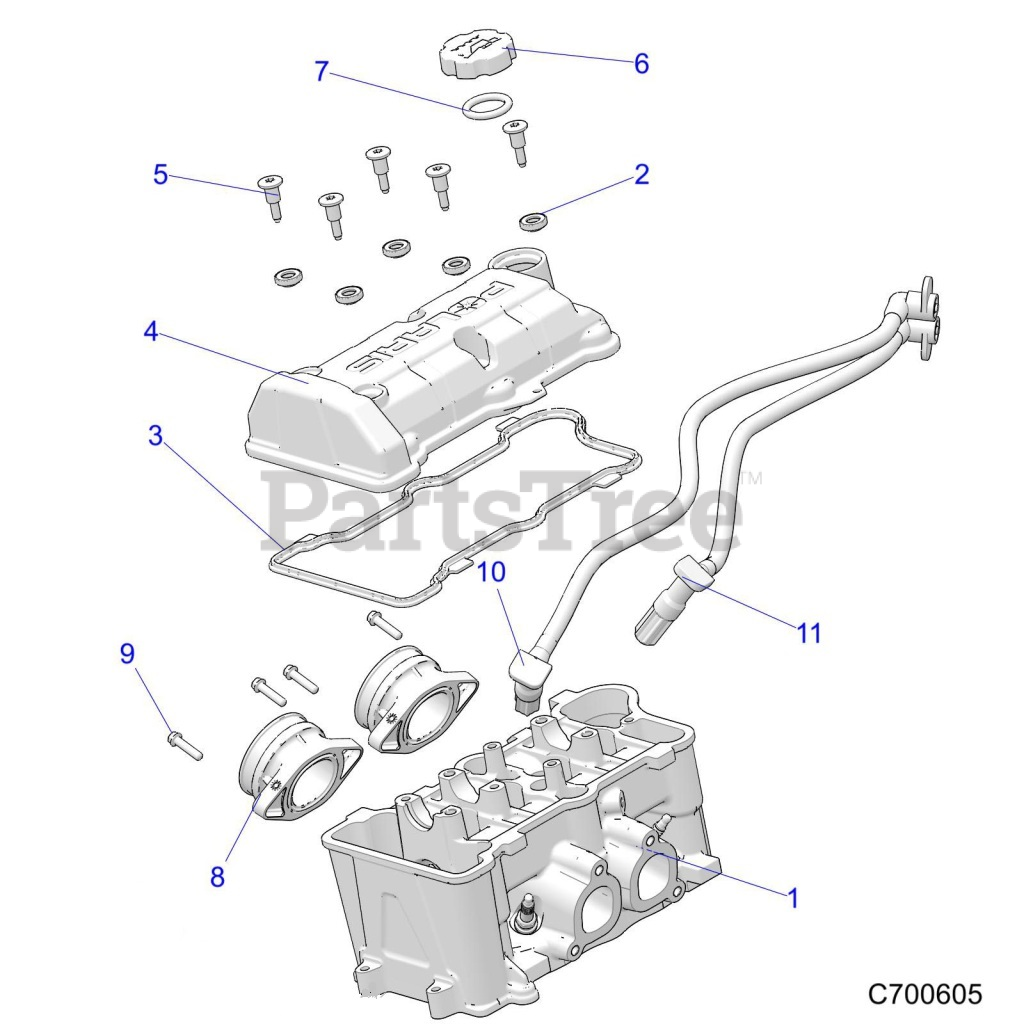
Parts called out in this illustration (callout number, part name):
1	SPARKPLUG-12MM
2	ISOLATOR-VALVE COVER
3	SEAL-VALVE COVER,2CYL,SOHC
4	COVER-VALVE,CAST,2CYL,SOHC
5	BOLT-SHLDR,M6X12X15
6	ASM-OIL FILL CAP
7	O-RING-FILL CAP
8	ADAPTER-MANIFOLD
9	SCR-HXFLG,M6X1.0X25,10.9
10	WIRE-SPARKPLUG,MAG
11	WIRE-SPARKPLUG,PTO
